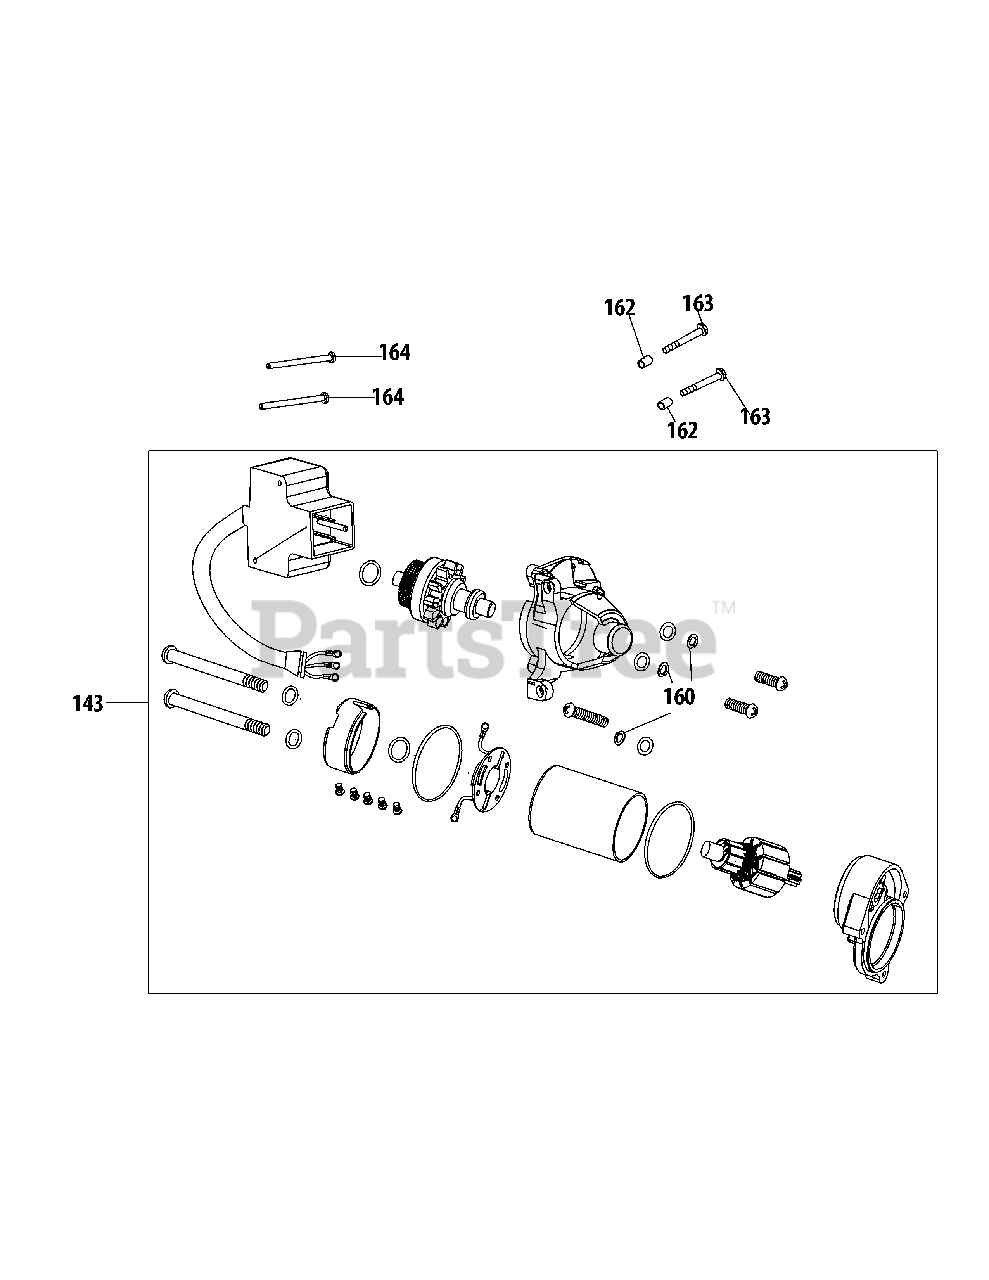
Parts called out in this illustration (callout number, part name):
143	Electric Starter
160	Spring Washer 5
162	Dowel Pin 8×8
163	Bolt M6×32
164	Bolt M4×55
